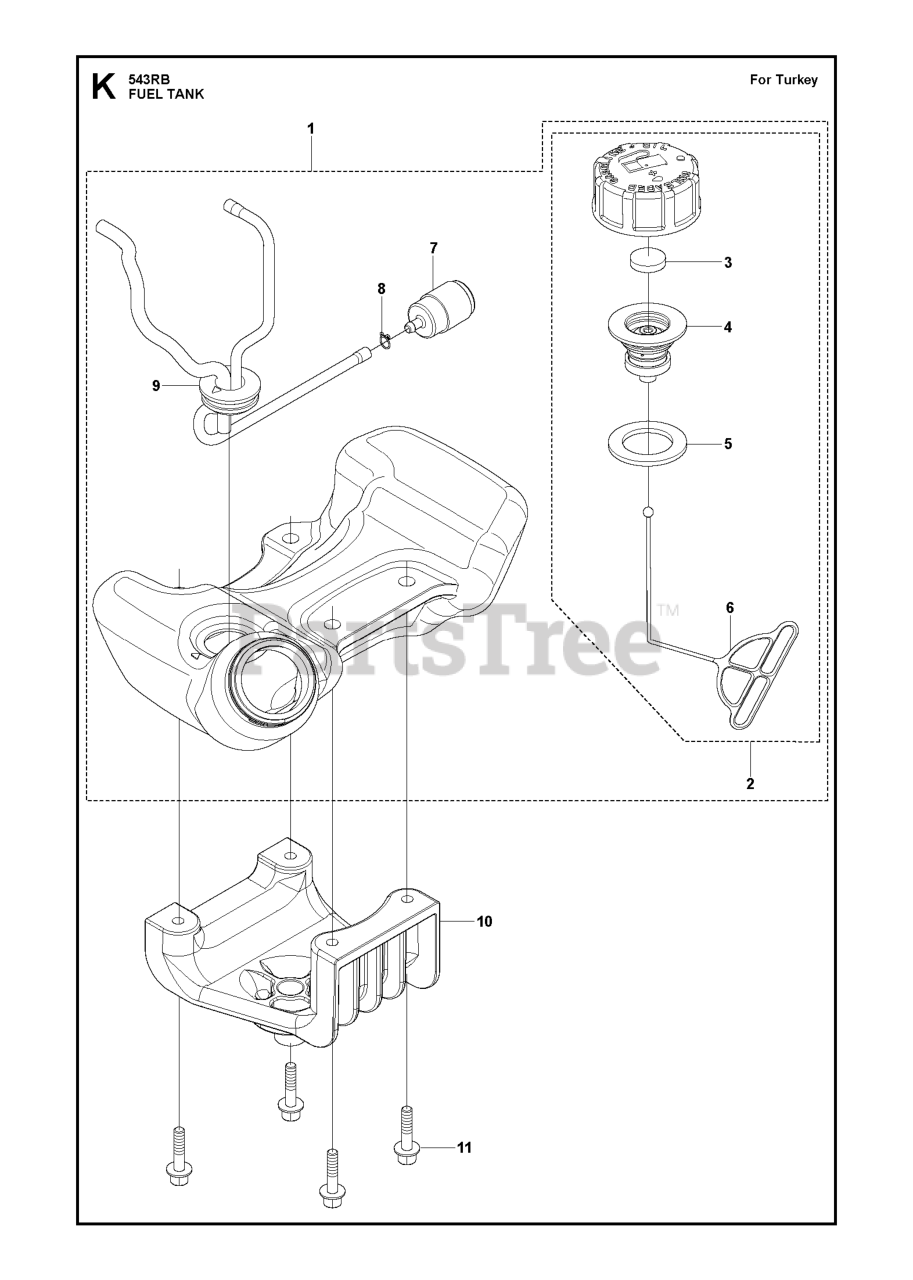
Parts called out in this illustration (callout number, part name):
2	ASSY FUEL CAP
3	FILTER
4	HOLDER-A
5	PACKING
6	STOPPER
7	FILTER
8	CLIP
9	PIPE COMP
11	BOLT M5X25
